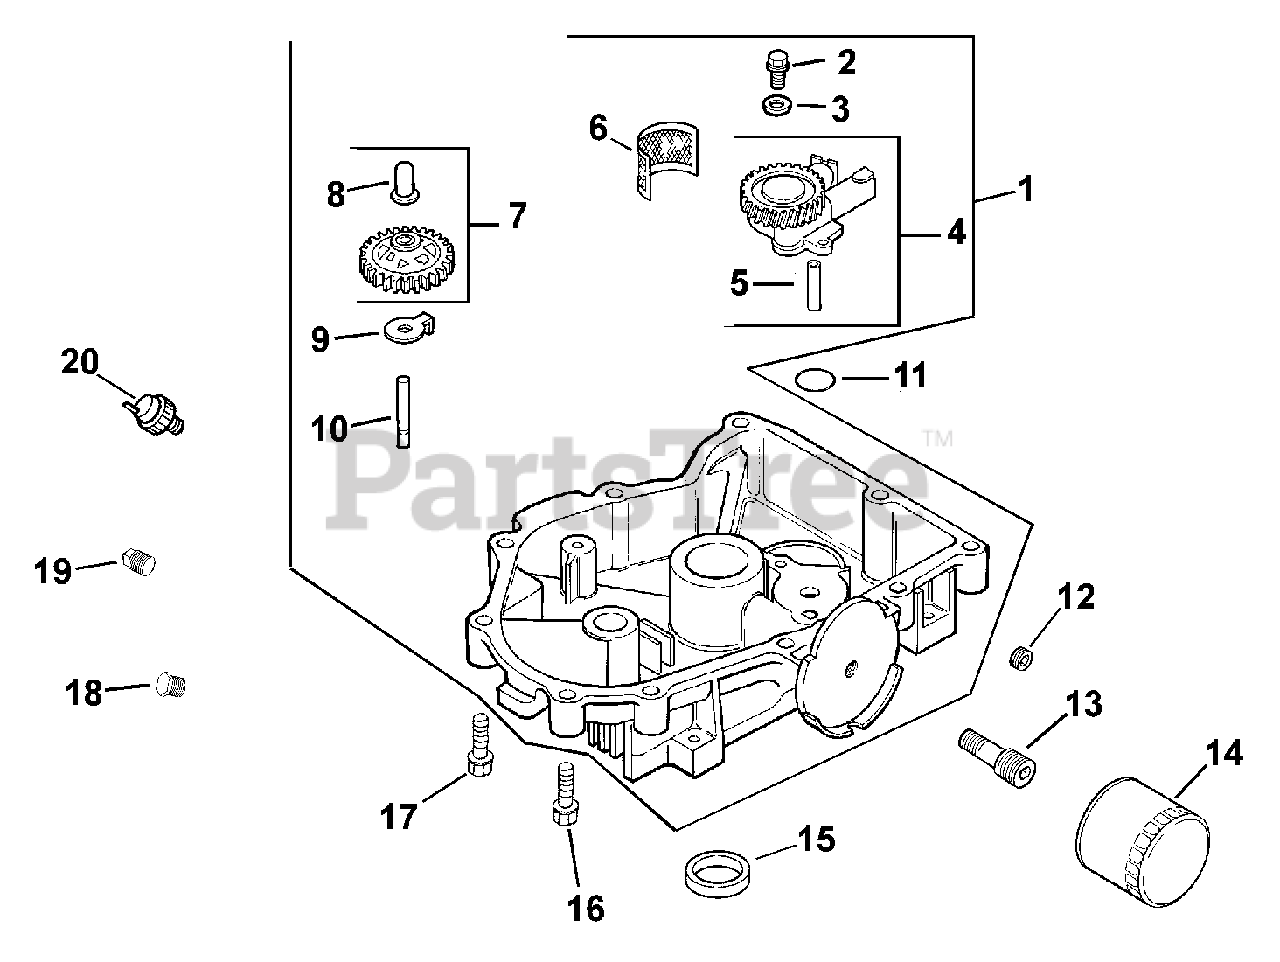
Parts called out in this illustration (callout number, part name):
1	PAN , OIL ASSEMBLY USE 24 199 32-S
2	SCREW,FLG THD FRM M6X1.0X25-(#25086395S)
3	WASHER, FLAT 6 MM
6	SCREEN, OIL
7	KIT, GOVERNOR GEAR W/PIN
8	PIN, GOVERNOR REGULATING
10	SHAFT, GOVERNOR GEAR
12	PLUG, PIPE CTSK 3/8"
13	NIPPLE, OIL FILTER
14	OIL FILTER
15	SEAL, OIL (KM)-USE 25 032 06-S
16	SCREW, HEX FLANGE -USE 24 086 17-S
17	SCREW, FLG M8X1.25X45
19	PLUG, SQ HD PIPE 3/8"
